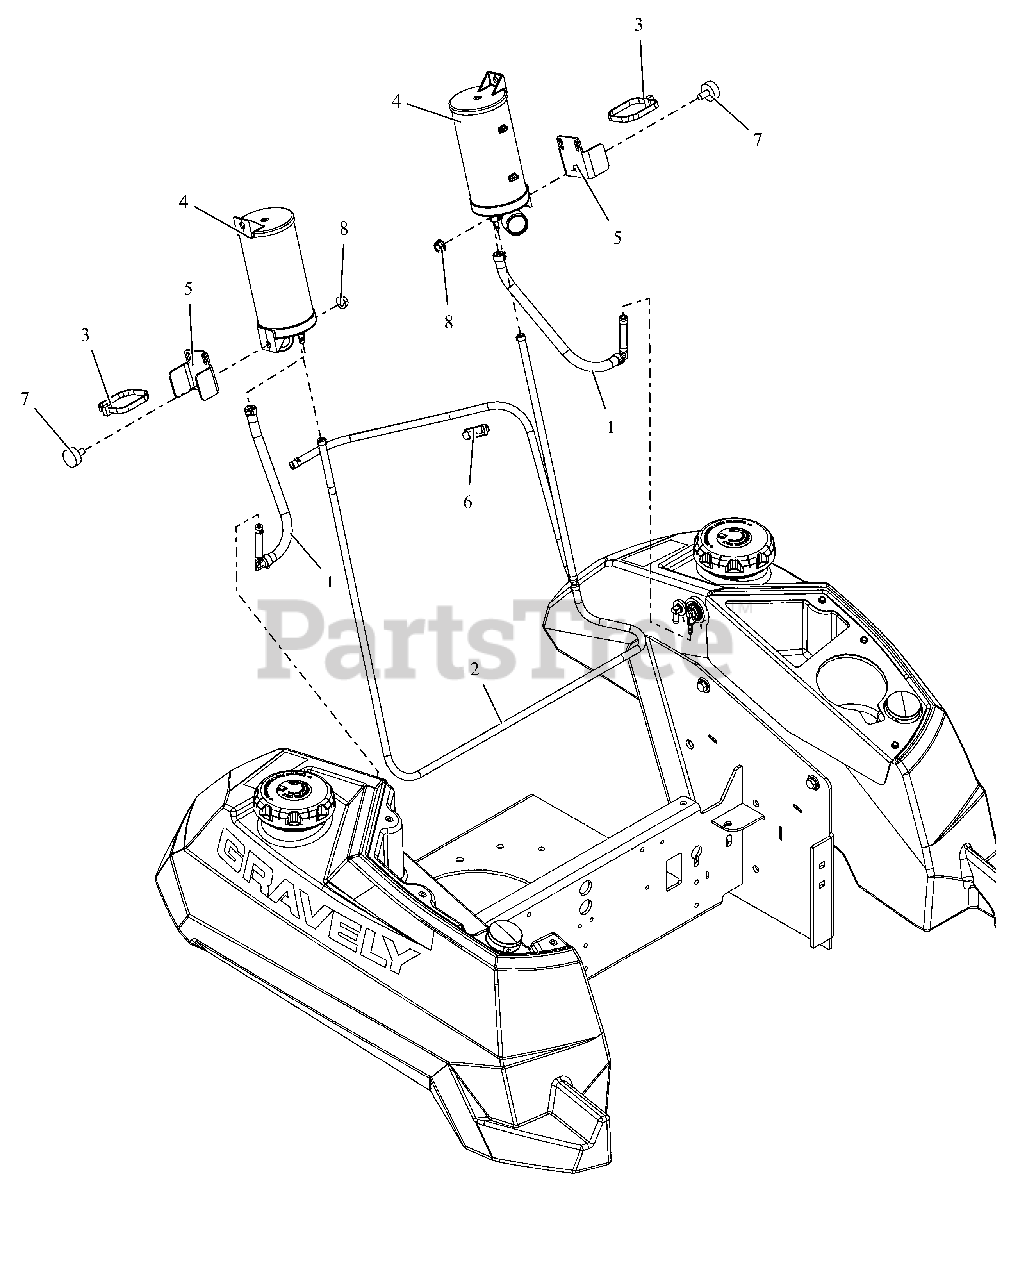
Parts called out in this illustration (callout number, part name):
1	ASM, CANISTER VENT LINE
2	ASM, VAPOR LINE (CARB)
3	TIE WRAP, 15.25" X 120 LBS
4	CANISTER, 400 CC CARB
5	CARB CANISTER MTG BRKT - BLACK
6	CLIP, T, .38-.50
7	BUMPER, RUBBER
8	@NUT-SPNLK-FLG .312-18 YWZC
